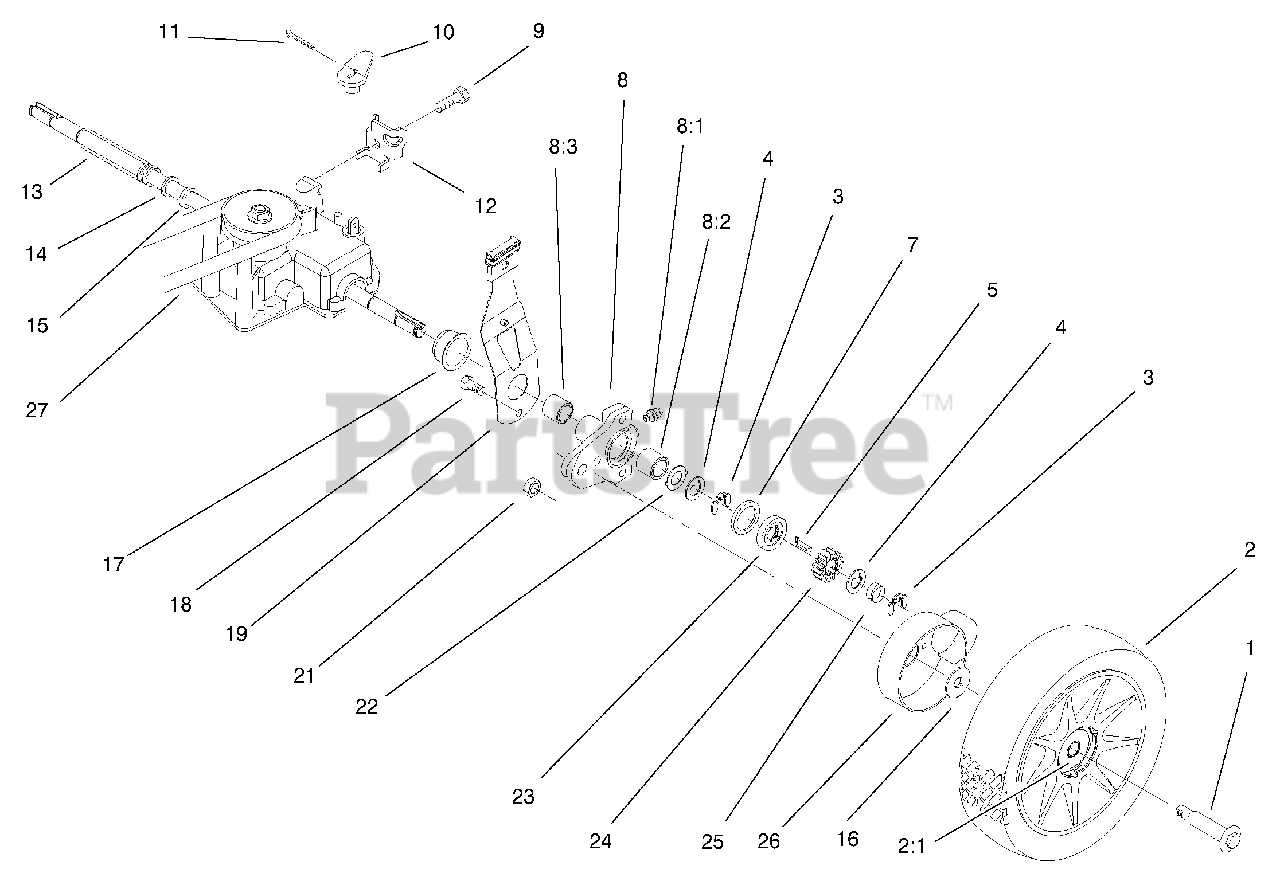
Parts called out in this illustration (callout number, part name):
1	Bolt-Shoulder
2	Wheel & Tire ASM
3	Ring-Klip
4	Washer-Thrust, Keyed
5	Key-Rocking, LH
7	Ring-Friction
8	Arm ASM-Rear Height Adjustment
8:1	Fitting-Zerk
10	Lever-Shift
11	Pin-Cotter
12	Clamp-Cable
13	Cover-Shaft, Drive
16	Washer-Stepped
17	Ring-Isolator
19	Rear Spring Arm ASM-LH
22	Washer-Arm, Pivot
23	Washer-Clutch
24	Gear-Pinion
25	Spring-Compression
26	Cover-Wheel
